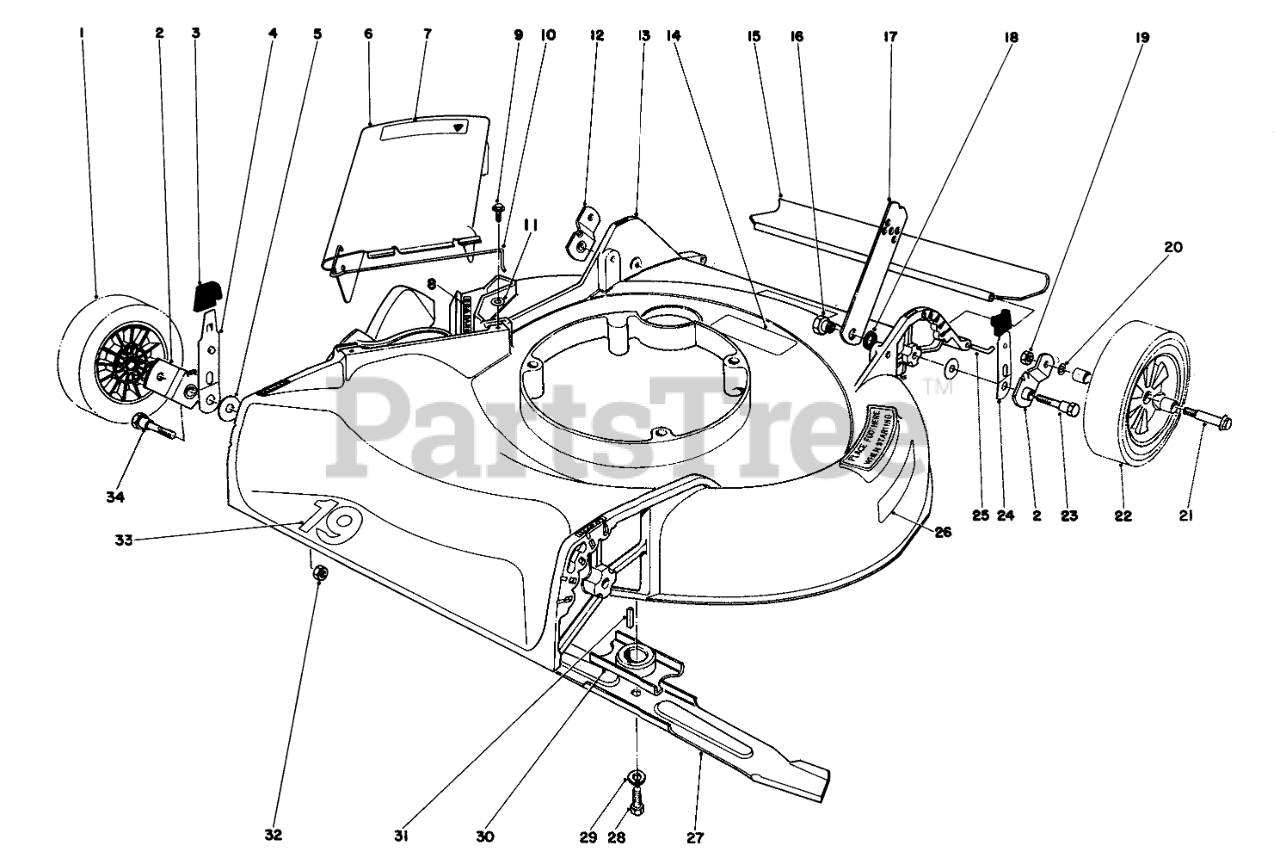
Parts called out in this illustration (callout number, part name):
1	WHEEL TIRE ASM 7 IN
2	Pivot Arm
3	KNOB-ARM
4	SPRING ARM ASM
5	Washer
6	Deflector-Cover Assembly (Incl. Ref. #7 & 10)
7	Decal-Caution
8	Decal-Danger
9	SCREW
10	SPRING HINGE
11	WASHER-FLAT
12	Pivot Arm
13	Housing (Model 16077) (Incl.Ref. #8, 14 & 26)
14	Decal-Warning
15	Rear Shield
16	HANDLE PIVOT NUT
17	Handle Latch
18	HANDLE LATCH SPACER
19	Nut
20	WASHER
21	BOLT-WHEEL
22	WHEEL TIRE ASM 8 IN
23	PIVOT SCREW
24	SPRING ARM ASM
25	SHIELD ROD
26	Decal-Step
27	Blade
28	SPECIAL SCREW
29	WASHER-LOCK
30	Blade Retailer
31	KEY-SQUARE
32	Nut
33	Decal-19" (Model 16077)
34	PIVOT SCREW
